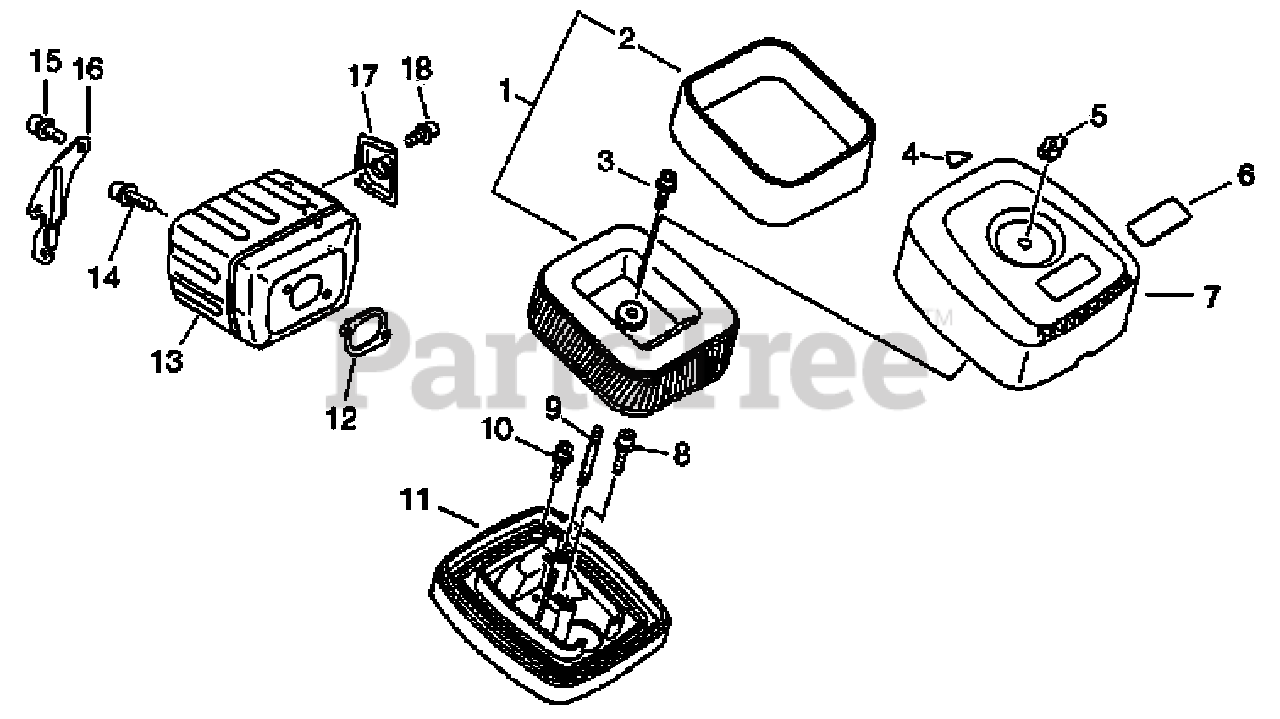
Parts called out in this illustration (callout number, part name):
1	FILTER, AIR
2	FILTER, AIR
3	SCREW - 5X16
6	LABEL - MODEL CSG-680
7	COVER, AIR FILTER
8	SCREW - 5X25
10	SCREW - 5X16
11	CASE, AIR FILTER
12	GASKET, EXHAUST
13	MUFFLER
14	SCREW - 5X20
15	SCREW - 5X10
16	BRACKET, MUFFLER
17	GUIDE, EXHAUST
18	SCREW - 4X10
